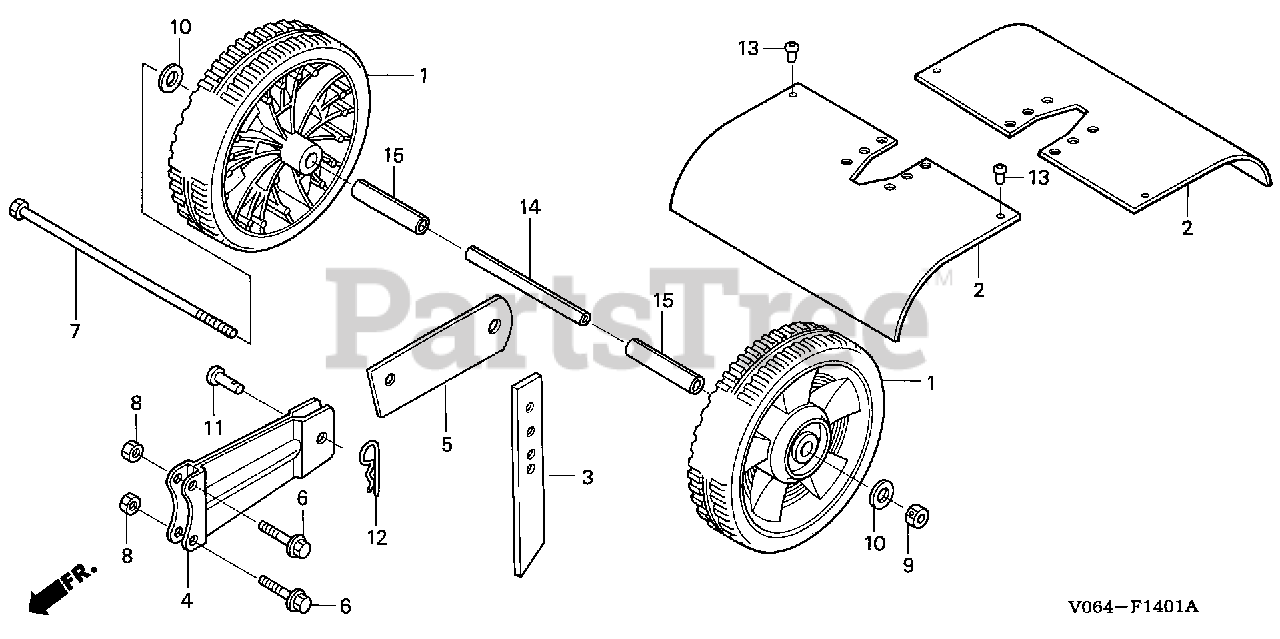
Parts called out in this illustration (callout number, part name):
1	WHEEL
1	WHEEL, RR.
2	FENDER, FR.
4	HOLDER, DRAG BAR
5	BAR, WHEEL
6	SCREW (1/4-20X1)
7	BOLT, HEX. (3/8-16X8)
8	NUT (1/4-20)
9	NUT, CENTERLOCK (3/8-16)
10	WASHER, FLAT (3/8")
11	PIN (5/16X7/8)
13	RIVET (5/32X1/8)
14	COLLAR, WHEEL (INNER)
15	COLLAR, WHEEL (OUTER)
